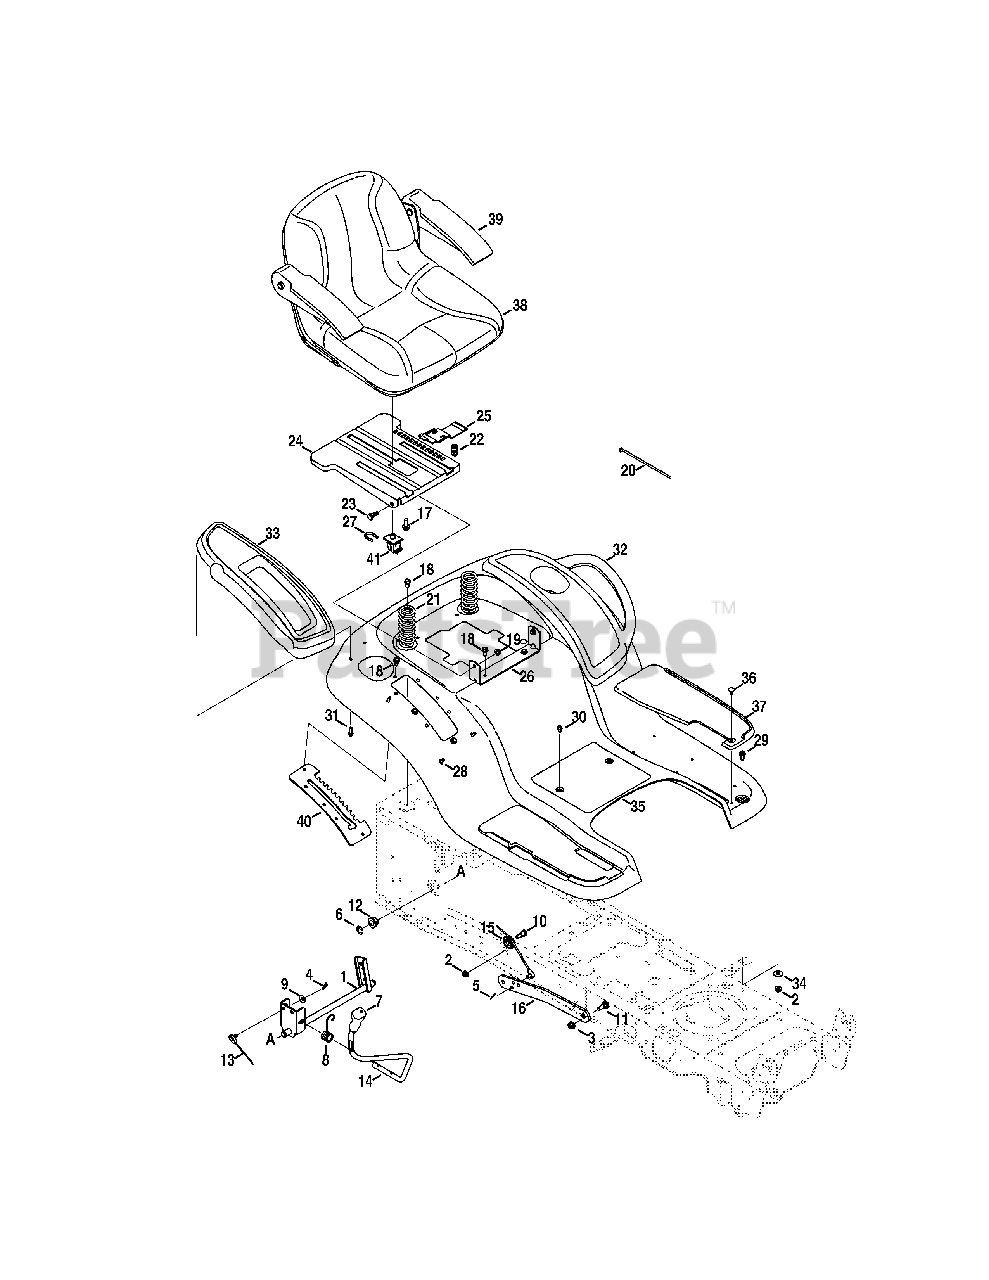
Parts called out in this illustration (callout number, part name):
1	Lift Shaft Assembly
2	Flangelock Nut, 5/16-18
3	Flangelock Nut, 3/8-16
4	Cotter Pin, .072 DIA. x 1.13 LG
5	Bow-Tie Cotter Pin
6	E-Ring, .625 DIA. SHAFT
7	Handle Grip
8	Torsion Spring
9	Spring Washer, .401 x .870 x .063
10	Shoulder Screw, .437 x .470:5/16-18
11	Shoulder Bolt, .500 x .270:3/8-16
12	Hex Flange Bearing
13	Lift Cable, 16.16 LG
14	Lift Handle
15	Pulley Roller Cable
17	Hex Head Flange, 3/8-16:.875
18	Taptite Screw, Lock Washer, 5/16-18:.750
19	Flangelock Nut, 5/16-18
20	Cable Tie, 3/16 x .05 x 7.4
21	Compression Spring, 1.71 x 3.735 x .238
22	Compression Spring, .68 x 1.065 x .055
23	Shoulder Screw, .437 x .268:5/16-18
24	Seat Mounting Bracket
25	Seat Adjustment Lever
26	Seat Pivot Bracket
27	Switch Retainer Clip
28	Hi-Lo Screw, Lock Washer, 1/4-15:0.50
29	Carriage Bolt, 5/16-18:.750
30	Taptite Screw, Lock Washer, 1/4-20:0.500
31	Hi-Lo Screw, Lock Washer, 1/4-15:0.750
32	LH Fender Cover
33	RH Fender Cover
34	Flat Washer, .344 x 1.00 x .063 HDN
36	Ratchet Clip
37	LH Foot Pad
37	RH Foot Pad
38	Seat
39	Armrests
40	Lift Bracket
41	Seat Switch
